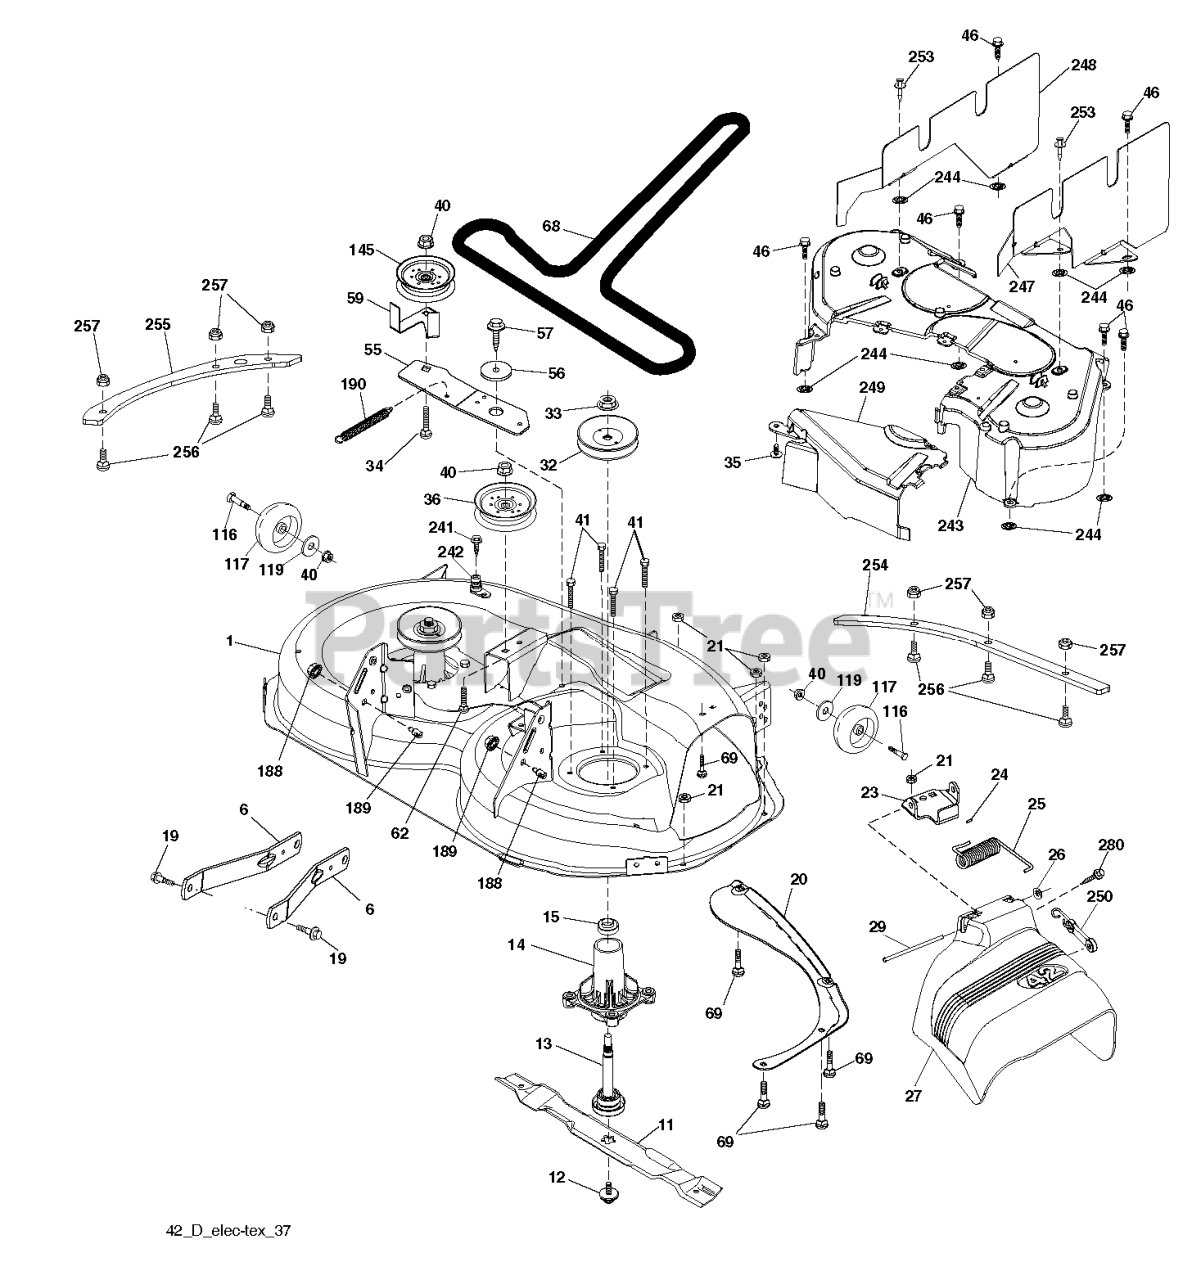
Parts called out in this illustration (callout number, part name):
1	DECK SVC 42"B 103 419175X498
6	ARM.SUSPENSION.MOWER.R
8	BOLT.WASHER.ASM.7/16-2
11	42" HI-LIFT BLADE
13	SHAFT.ASM.MDRL.N/GREASE.38
14	RP.HOUSING.MANDREL.4PT.
19	BOLT.SHOULDER
20	BAFFLE.VORTEX
21	LOCKNUT
23	BRKT.DEFLECTOR.38"2005+
24	CAP-SLEEVE LT
25	SPRING.TORSION.DEFLECT
26	NUT PUSH M
27	DEFLECTOR ASM.42"TEX.FRENCH
29	ROD.HINGE
31	WASHER.SPACER.MANDREL
32	PULLEY/MANDREL
33	NUT.FLANGE.LOCK.TOP
34	BOLT.3/8-16X1.50
35	FASTENER.XMAS.TREE
36	PULLEY.IDLER.2006
40	NUT LOCK FLG 3/8-16 UNC
41	BOLT.HEX.WASHR.HED.313-18X1.19
46	SCREW.1/4-20X5/8
55	IDLER.ARM.42"
56	SPACER.RETAINER
57	SCREW 3/8-16X1
59	GUARD, BELT
62	BOLT
68	BELT V SECONDARY
69	BOLT
116	BOLT M
117	WHEEL.GAGE.HALF.SPOKED
119	WASHER.5/16.FLAT.STE.STD.
145	PULLEY.IDLER.48"PRIMARY
188	STUD.FASTNER.W/ANTI-ROTATE
189	NUT LOCK HEX FLANGE 5/16-18
190	SPRING.MOWER.DRIVE.ELECTRIC
241	SCREW.TT.#10-32X.5.3/8.FLANGE
242	PORT.WASHOUT
243	COVER DECK
244	PALNUT 1/4
247	SHIELD DECK RIGHT
248	SHIELD DECK LEFT
249	COVER CABLE CLUTCH
250	ELASTIC STRAP KIT
253	SCREW
254	PLATES.RENFRC.42DECK.PT431FRNT
255	PLATES.RENFRCE.42DECK.X431SIDE
256	RHSNB, 1/4-20 X 1, GR5
257	NUT T
280	SCREW 3/8-16X1/2
